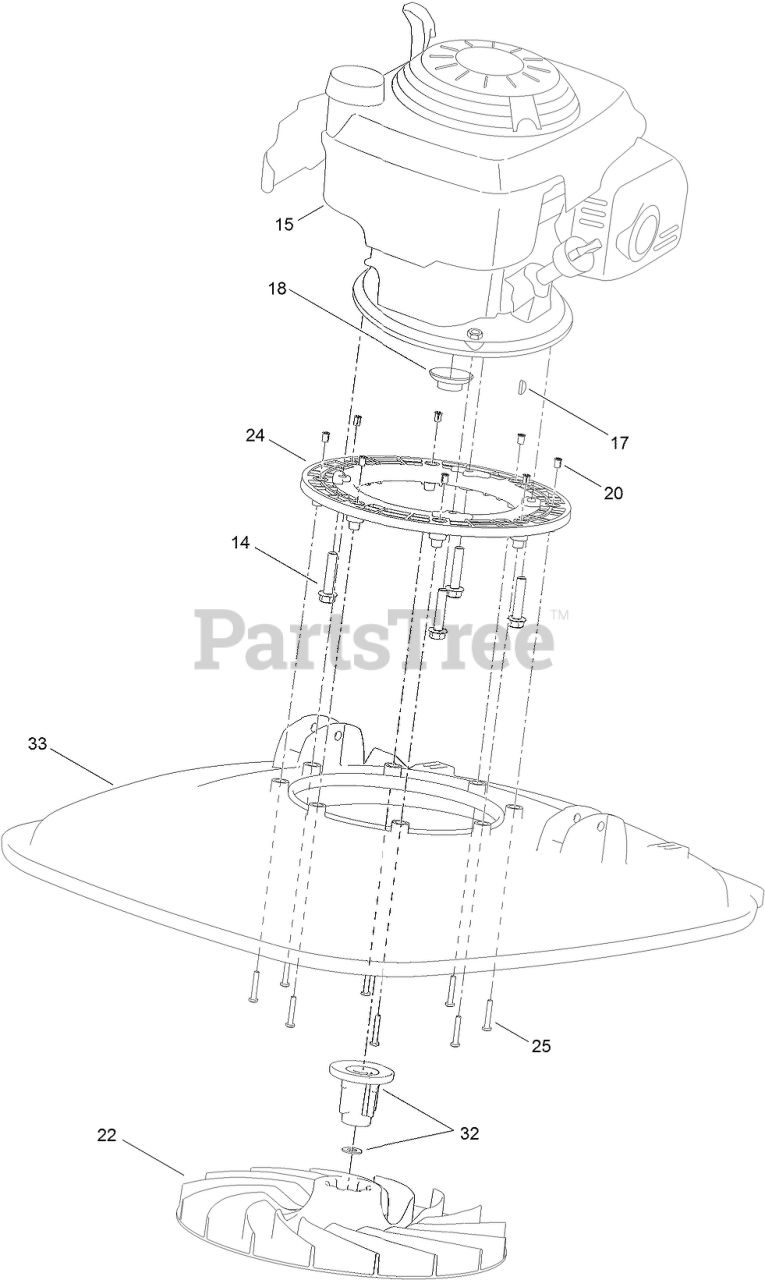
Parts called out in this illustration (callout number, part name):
14	SCREW-TAPTITE
15	ENGINE-Honda
17	KEY-WOODRUFF
18	PROTECTOR-SEAL, OIL
20	INSERT-BRASS
22	IMPELLER
24	FRAME-MOUNTING, ENGINE
25	SET-SCREW
32	DRIVE AND SPACER ASM
33	DECK-DRILLED
